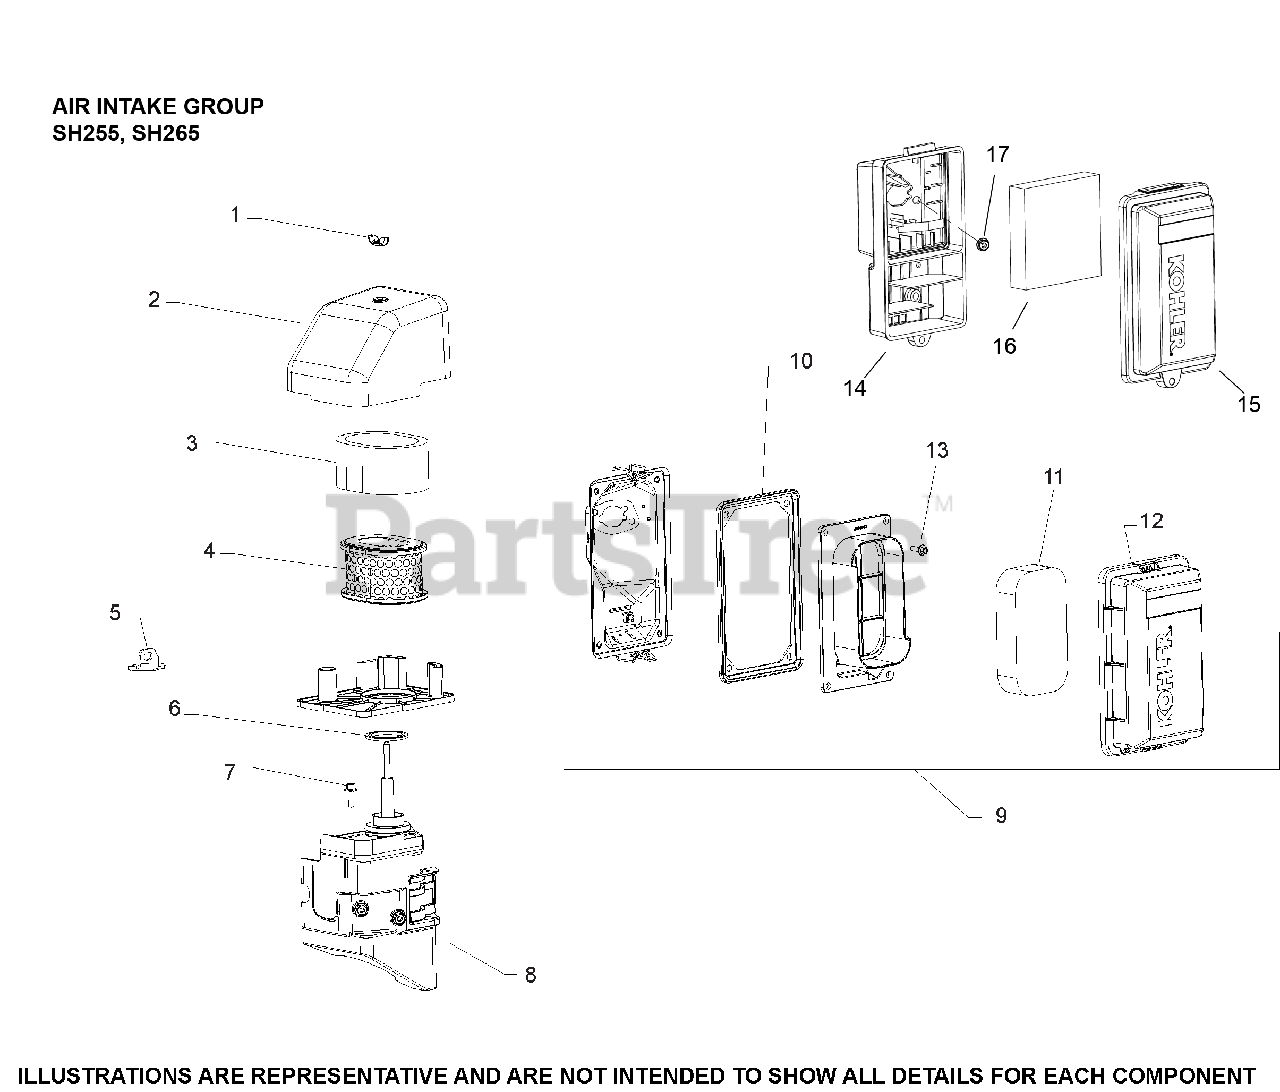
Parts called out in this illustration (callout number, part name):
5	PLATE, INTAKE SUPPORT
9	KIT, AIR CLEANER ASSY
10	GASKET, AIR FILTER
11	ELEMENT, AIR FILTER
13	SCREW, HEX FLANGE
17	NUT, HEX FLANGE LOCK (M6)
